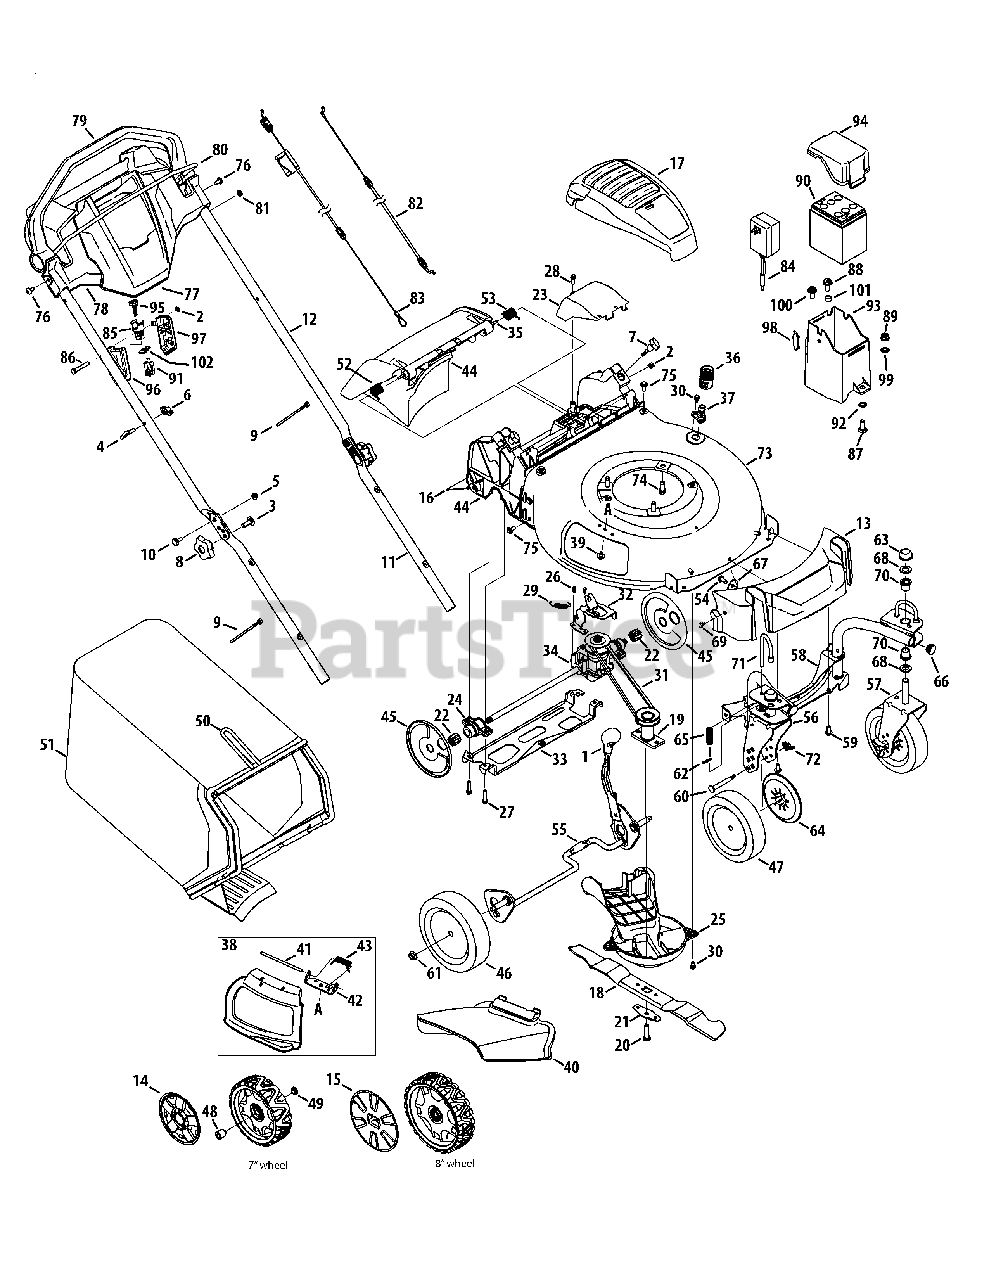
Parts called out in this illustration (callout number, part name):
1	Adjustment Knob
2	Nut, Sq., 1/4-20
3	Carriage Screw ,5/16-18
4	Rope Guide
5	Nut, Flange Lock, 1/4-20
7	Wing Nut
9	Cable Tie
10	Shdr. Screw, .375 x .126 x 1/4-20
11	Lower Handle
12	Upper Handle
13	Front Cover
14	Hubcap, 7"
15	Hubcap, 8"
16	Trail Shield
17	Engine Shroud
17	Screw, #10-16 X 1.25
18	Mulching Blade
19	Blade Adapter
20	Screw, 3/8-24 x 1.50
21	Blade Bell Support
22	Spur Gear, 10T
23	Transmission Cover
24	Bearing Assembly
25	Engine Baffle
26	Screw, Hex Washer, .159 x .43
27	Screw, 1/4-15 x 1.25
28	Screw, 1/4-15 x .750
29	Exten. Spring, 2.405
30	Screw, Shldr., 1/4-20 x .50
32	Transmission Bracket
33	Rear Support Bracket
34	Transmission Assembly
36	Water Nozzle Adapter
37	Water Nozzle
38	Mulch Plug (Incl. 41-43)
40	Side Discharge Chute
42	Chute Deflector Bracket
43	Torsion Spring
44	Rear Discharge Door Assembly
45	Wheel Dust Cover
46	Rear Wheel, 8 x 2
47	Front Wheel, 7 x 2
48	Caster Hub, Long
49	Caster Hub, Short
50	Grass Catcher Frame
52	Torsion Spring - RH
53	Torsion Spring - LH
54	Self Tapping Screw, 5/16-18 x .750
55	Rear Axle Assembly
56	Caster Bracket Assembly, RH
57	Caster Bracket Assembly, LH
58	Caster Bracket Assembly
59	Screw, 5/16-14 x .750
60	Caster Axle, .374 Dia. x 2.59
61	Flange Lock Nut, 3/8-16
62	Cotter Pin, .072 Dia. x 1.13 Lg.
63	Push Cap, 5/8
64	Dust Cover, 7"
65	Compr. Sprng., .531 OD x 1.75 Lg
67	Washer, Flat, .330 x 1.25 x .06
68	Flat Washer, .640 x 1.12 x .125
69	Shdr. Screw, .50 x 1/4-20
70	Flange Bearing, .631 ID
71	Lock Pin: Front Wheel
72	Wing Nut, 1/4-20 w/Bell Washer
73	21" Deck
74	Screw, tt, 3/8-16 x 1.00
75	Screw, 5/16-14 x .750
76	Screw, 1/4-14 x .625
77	Trim Console
78	handle Console
79	Drive Handle
80	Blade Control
81	Shoulder Spacer, .18 x .315 x .09
82	Control Cable
83	Drive Cable
84	Battery Charger
85	Key Switch
86	Screw, 1/4-20 x 1.75
87	Bolt, Carr., 5/16-18 x 1.00
88	Screw, 5/16-14 x .750
89	Nut, Flglk., 5/16-18
90	Battery
91	Plunger Switch
92	Speed Nut
93	Battery Housing
94	Battery Housing Top
96	Electric Start Housing, RH
97	Electric Start Housing, LH
98	Lid Seal
99	Washer, Bell, .340 x .872 x .080
100	Scr., Sldr., 5/16-14 x .972
101	Spacer, .340 x .460 x .246
102	Retainer Bracket
